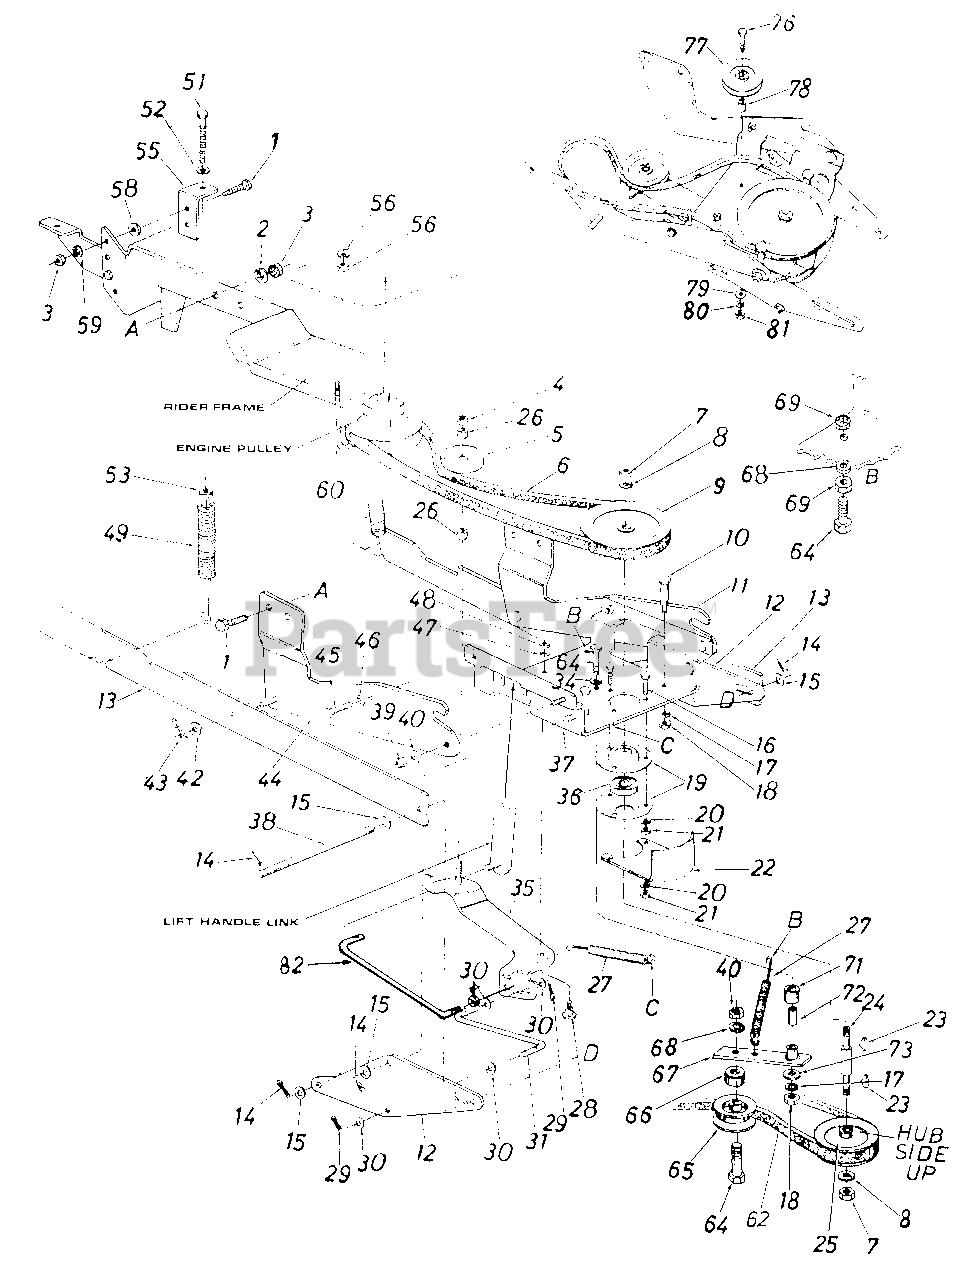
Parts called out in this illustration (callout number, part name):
1	Hex Bolt 1/4-28 x .75" Lg. Grade 5
2	L.-Wash. 1/4" I.D.*
3	Hex Nut 1/4-28 Thd.*
4	Hex Cent. L-Nut 3/8-16 Thd.
5	Idler Pulley
6	"V"-Belt 1/2 x 49" Lg.
7	Hex Jam Nut 5/8-11 Thd.
8	L Wash. 5/8 I.D.*
9	6.501' O.D. x 5/8 Pulley
10	ShouIder BoIt
11	Channel Supporting Brkt.-R.H.
12	Linkage Brkt.
13	Linkage Arm Ass'y.
14	Intern. Cotter Pin .50 Dia.*
16	Hex Bolt 5/16 x 1.25" Lg.
17	L. Wash. 3/8" I.D.*
18	Hex Jam Nut 3/8-16 Thd.
19	Bearing Housing
20	L.-Wash. 5/16" I.D.*
21	Hex Nut 5/16-18Thd.*
24	Pulley Spindle
25	5/8 Pulley-6.28 I.D. x 5.56 O.D.
26	Spacer .383 I.D. x .503 O.D. x .562 Lg.
27	Extension Spring .54 O.D. x 5.25"
28	Shoulder Bolt
29	Cotter Pin 3/32" Dia. x 1.0"*
34	Hex Sems Scr. 5/16-18 x 1.0" Lg.*
35	Clutch Idler Brkt. Ass'y.
36	Ball Bearing
37	Channel Ass'y.
38	Lift Handle Shaft
39	Hex Jam Nut 3/8-16 Thd.
40	L.-Wash. 3/8" I.D.*
43	Intern. Cotter Pin .50" Dia. *
44	Channel Supporting Brkt.-L.H.
45	Hex Bolt 3/8-16 x x 1.0" Lg. *
46	L. Wash. 3/8" I.D.*
47	L. Wash. 5/16" I.D.*
48	Hex Nut 5/16-18 Thd.*
49	Helper Spring
51	Hex Scr. 5/16-18 x 2.0" Lg. SpeciaI
52	Bell Wash. .345 I.D. x .88 O.D. x .06
53	Spring Insert
58	Fl.-Wash. .264" I.D.
59	L.-Wash. 1/4" I.D.*
60	J-Bolt 5/16-18 Thd.
62	"V"-Belt 1/2 "A" x .89" Lg.
64	Hex Bolt 3/8-16 x 2.0" Lg.
65	Idler Pulley
66	Spacer .385 I.D. x .503 O.D. x .562" Lg .
67	Idler Arm Ass'y.
68	L.-Wash. 3/8" I.D.*
69	Hex Jam Nut 3/8-16 Thd.
71	Hex Bolt 5/16-19 x 1-1/4"
72	Spacer .3775 I.D. x .60 O.D. x 8.3 Lg.
73	Fl.-Wash. 3/8 I.D. x l" O.D. x 1.27
76	Hex Bolt 3/8-16 x 2.5" Lg. (Grade 5)
77	Idler Pulley .38 I.D. x 3.06 O.D.
78	Spacer .385 I.D. x .630 O.D. x .76 Lg.
79	Fl.-Wash. .39 I.D. x 1 3/4 O.D. x 3/16"
80	L-Wash. 3/8" I.D.*
81	Hex Nut 3/8-16 Thd.*
82	Clutch Control Rod 13.67" Lg.
